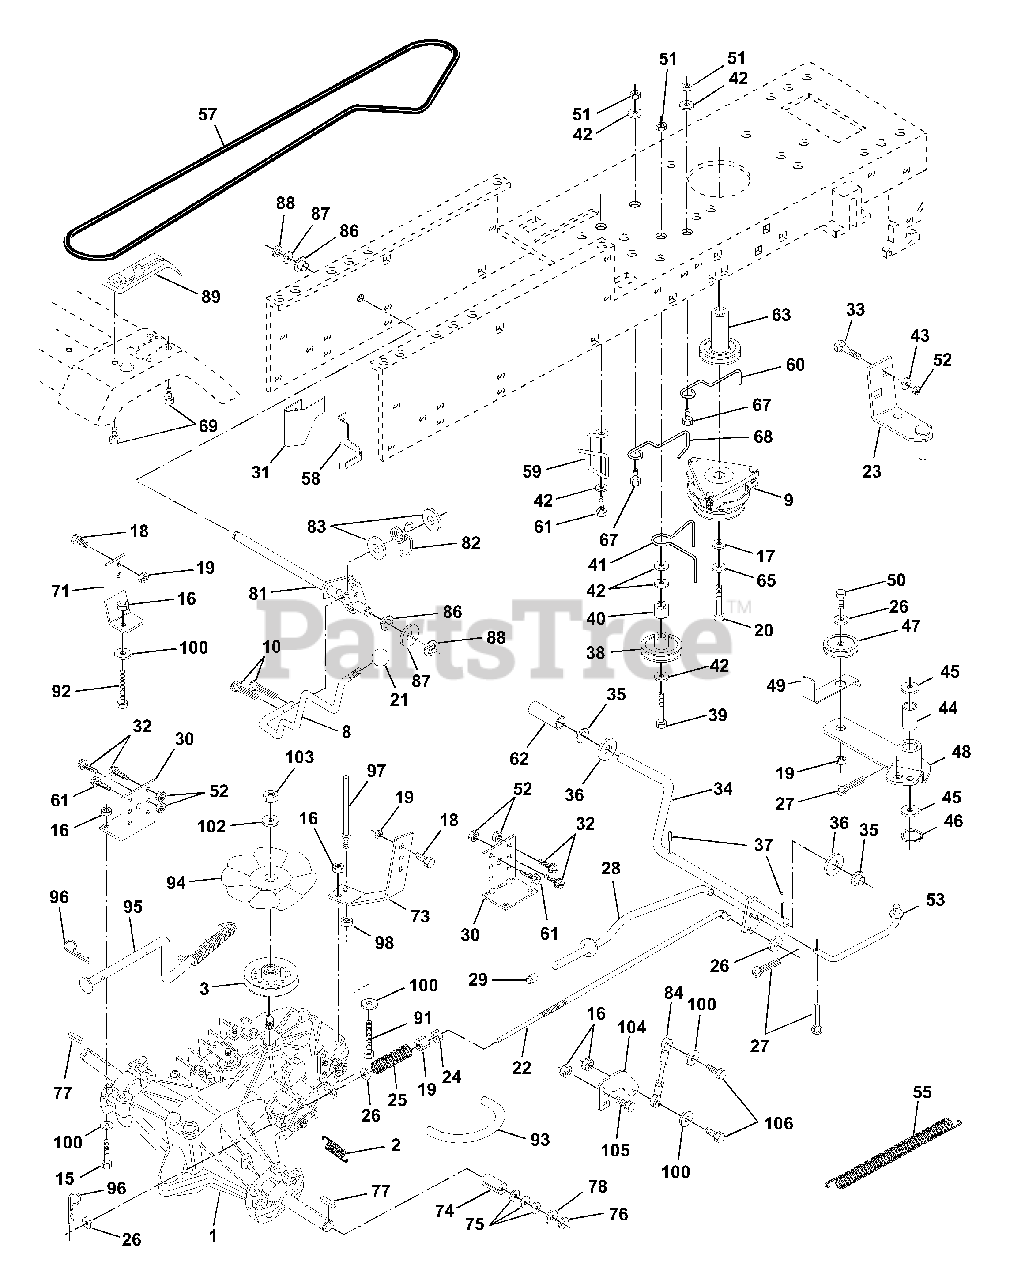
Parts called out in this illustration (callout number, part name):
1	Transaxle Assembly
2	Spring, Return, Brake
3	Pulley, Transaxle
8	Rod Shift Fender YT
9	Clutch, Electric
10	Pin Cotter 1/8 x 1 CAD
15	Bolt Fin Hex 5/16-18 Unc
16	Nut Lock Hex W/Ins. 5/16-18 Unc P
17	Washer 1-1/2 OD x 15/32 ID x .250
18	Bolt Fin Hex 3/8-16 Unc x 1 Gr. 5
19	Nut Lock Hex W/Wsh 3/8-16 Unc
20	Bolt, Hex
21	Knob, Duckhead 1/2-13
22	Rod, Brake Hydro
23	Bracket, Asm Mtg Clutch
24	Nut
25	Spring, Brake Rod
26	Washer
27	Pin Cotter 1/8 x 3/4 CAD.
28	Rod, Parking Brake
29	Cap, Parking Brake
30	Bracket, Transaxle
31	Keeper Belt Lh
32	Bolt Hex Hd 5/16-18 Unc x 3/4
33	Bolt Carriage 5/16-18
34	Shaft, Foot Pedal
35	Bearing, Nylon
37	Pin, Roll
38	Pulley, Idler, Flat
40	Spacer, Split
41	Keeper, Belt Retainer
42	Washer 13/32 x 13/16 x 12 Gauge
43	Washer 11/32 x 5/8 x 12 Ga.
44	Bearing, Nylon
45	Washer, Hardened
46	Ring, Klip
47	Pulley, Idler, V-Groove
48	Bellcrank Assembly
49	Retainer, Belt
50	Bolt
52	Nut, Crownlock 5/16-18
53	Link, Clutch
55	Spring, Return, Clutch
57	V-Belt, Ground Drive
58	Keeper Belt Lh Hydro 0750. 18/20"
59	Keeper, Center Span
60	Keeper Belt Engine
61	Screw Thdrol. 3/8-16 x 3/4 Ty. TT
62	Cover, Pedal
63	Pulley, Engine
65	Washer
67	Bolt
68	Keeper Belt Engine
71	Strap Torque Lh Hydro 18/20" T
73	Strap Torque Rh Hydro 18/20" T
74	Spacer, Split
75	Washer 25/32 x 1-1/4 x 16 Gauge
77	Key, Square
78	Washer 25/32 x 1-5/8 x 16 Gauge
81	Shaft Asm. Cross Hydro 20" Tires
82	Spring Torsion T/A
83	Washer 17/32 x 3/4 x 16 Ga.
84	Rod, Tie Hydro 20" Tires
86	Bushing Rod Steering 629/632 ID
87	Washer 21/32 x 1-1/4 x 16 Ga.
88	Ring Klip #5304-62
89	Console, Shift
91	Bolt Fin Hex 5/16-18 x 2-1/4
92	Bolt Fin Hex 5/6-18 Unc x 1-1/2
93	Line Fuel Hydro 4"
94	Fan, Hydro 7"
95	Control Arm, Bypass Hydro
96	Retainer Spring 1" Zinc/Cad
97	Keeper Belt Rh Hydro 0750. 18/20"
98	Nut Keps Hex 3/8-16 Unc
100	Washer 11/32 x 3/4 x 16 Ga.
102	Washer Belleville .501D x 1.50D
103	Nut Nylon Insert 1/2-20 Unf.
104	Arm, Control Hydro
105	Screw Cap Hex 5/16 x 18 x 1
106	Bolt Fin Hex 5/16-18 Unc x 1-1/4
